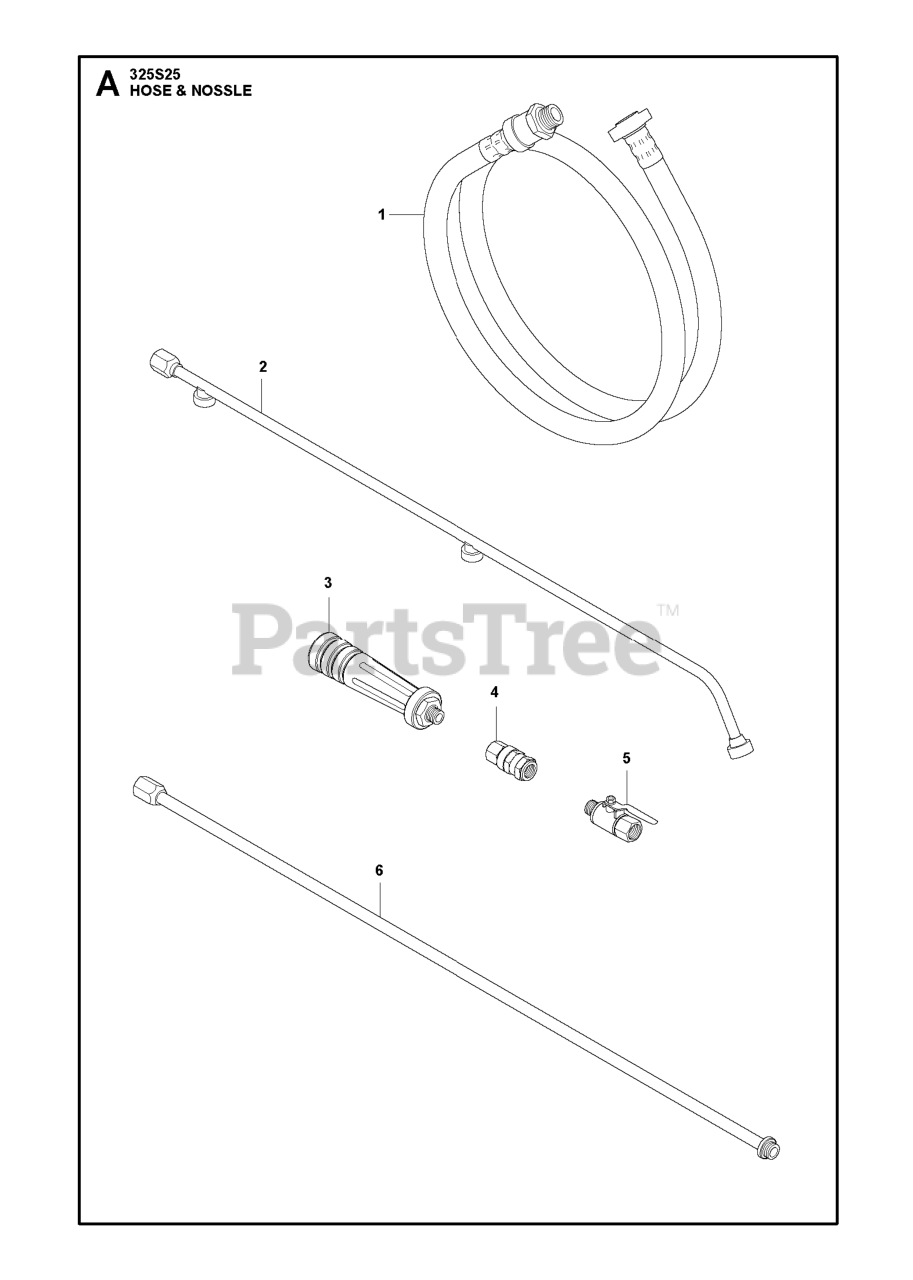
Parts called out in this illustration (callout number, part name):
1	HOSE (PVC+FIB+PE)
2	NOZZLE 3HOLE
6	NOZZLE PIPE
